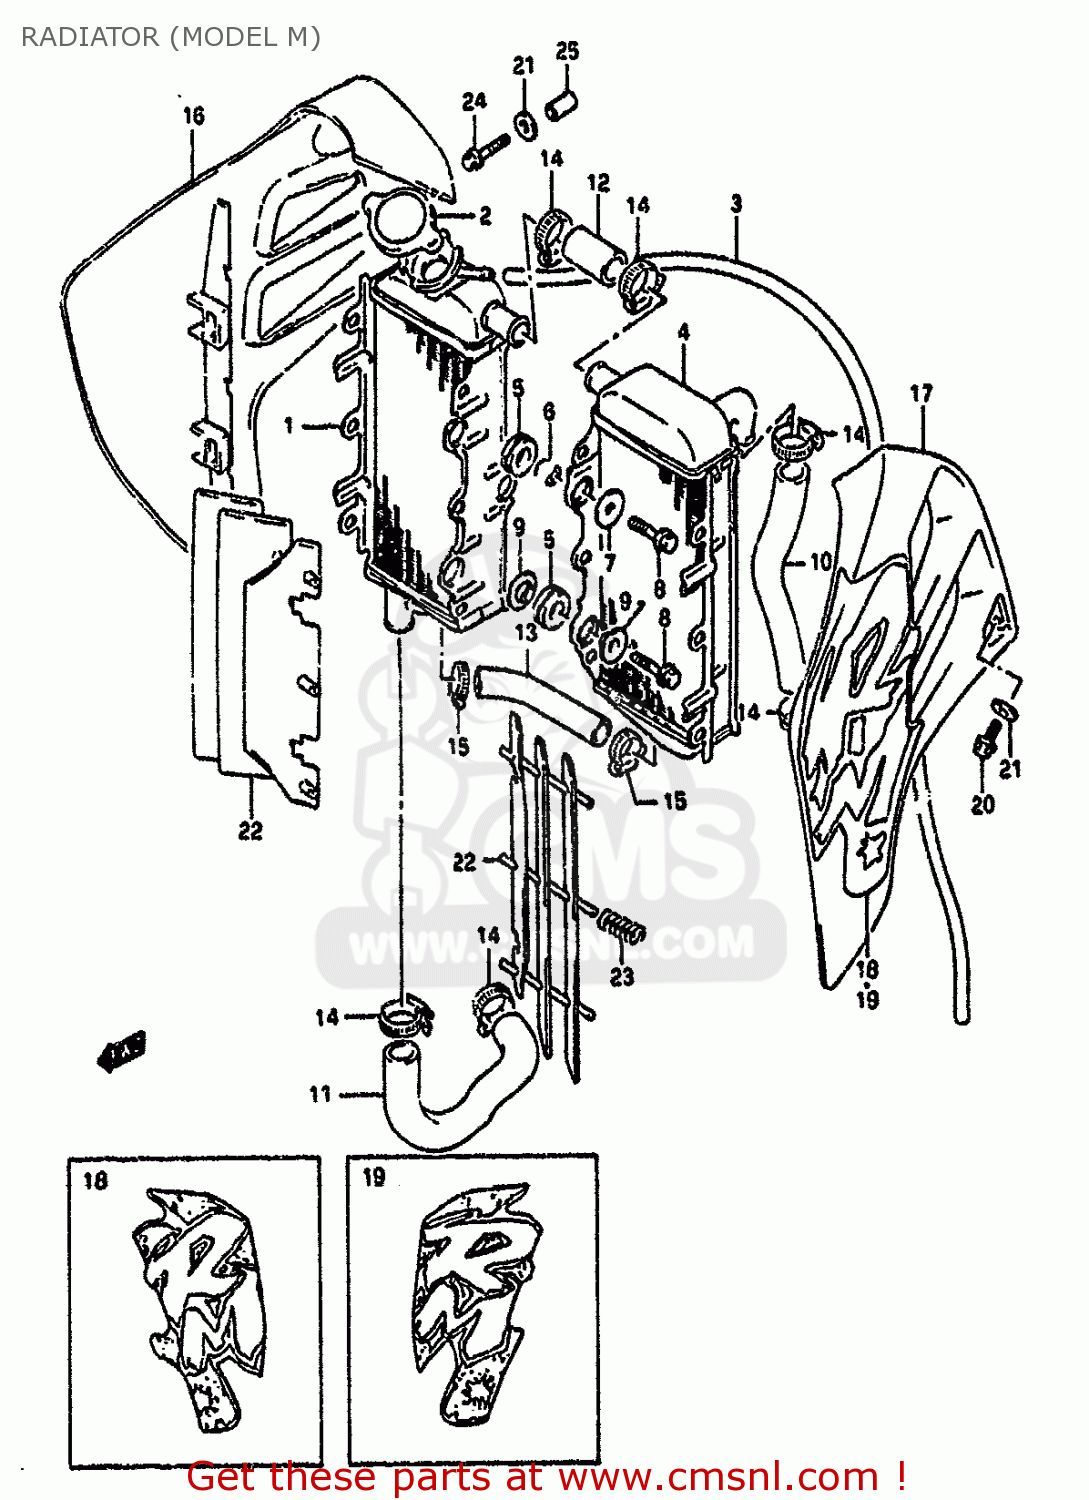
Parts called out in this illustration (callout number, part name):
1	RADIATOR COMP,WATER,RIGHT
2	CAP,RADIATOR 1.1
3	HOSE
4	RADIATOR COMP,WATER,LEFT
5	CUSHION,RADIATOR LWR
6	SPACER(6.5X10.5X12)
7	WASHER (6.5X24X1.2)
8	BOLT
9	WASHER,RDTR SPRT
10	HOSE,RADIATOR INLET
11	HOSE,RADIATOR
12	HOSE,RADIATOR JOINT NO.1
13	HOSE,WATER
14	CLAMP
15	CLAMP
16	COVER,RADIATOR,R
17	COVER,RADIATOR,L
18	EMBLEM,RADIATOR COVER RH
19	EMBLEM,RADIATOR COVER LH
20	BOLT
21	GASKET(6.5X20X1.5) (NAS)
22	LOUVER,RADIATOR
23	SPRING
24	BOLT
25	SPACER(6.4X10X22)
